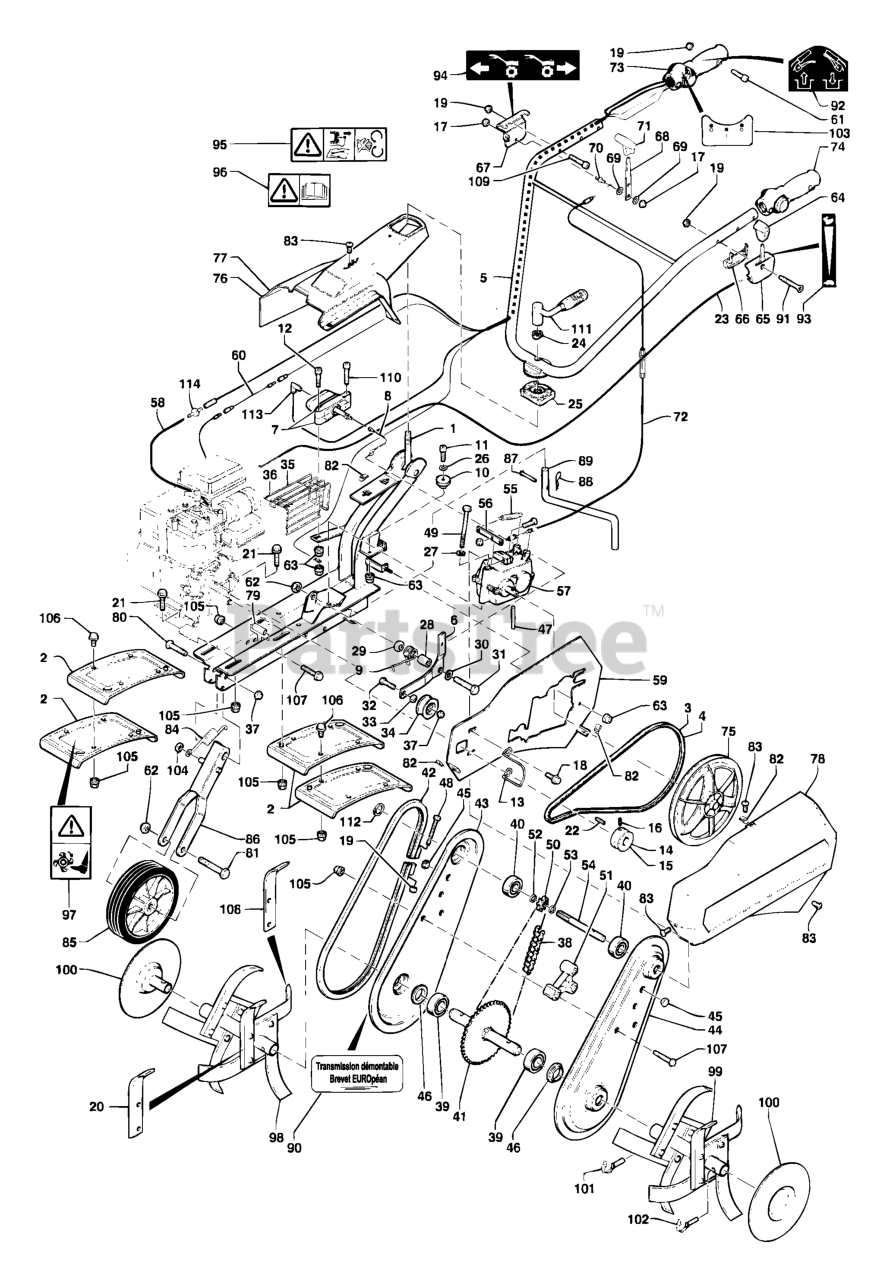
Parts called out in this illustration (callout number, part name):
6	ARM
38	DRIVE CHAIN
46	SPACER SLEEVE
65	THROTTLE TRIGGER
66	THROTTLE CONTROL
85	WHEEL
88	COTTER PIN
112	RETAINING RING
113	CONNECTION
